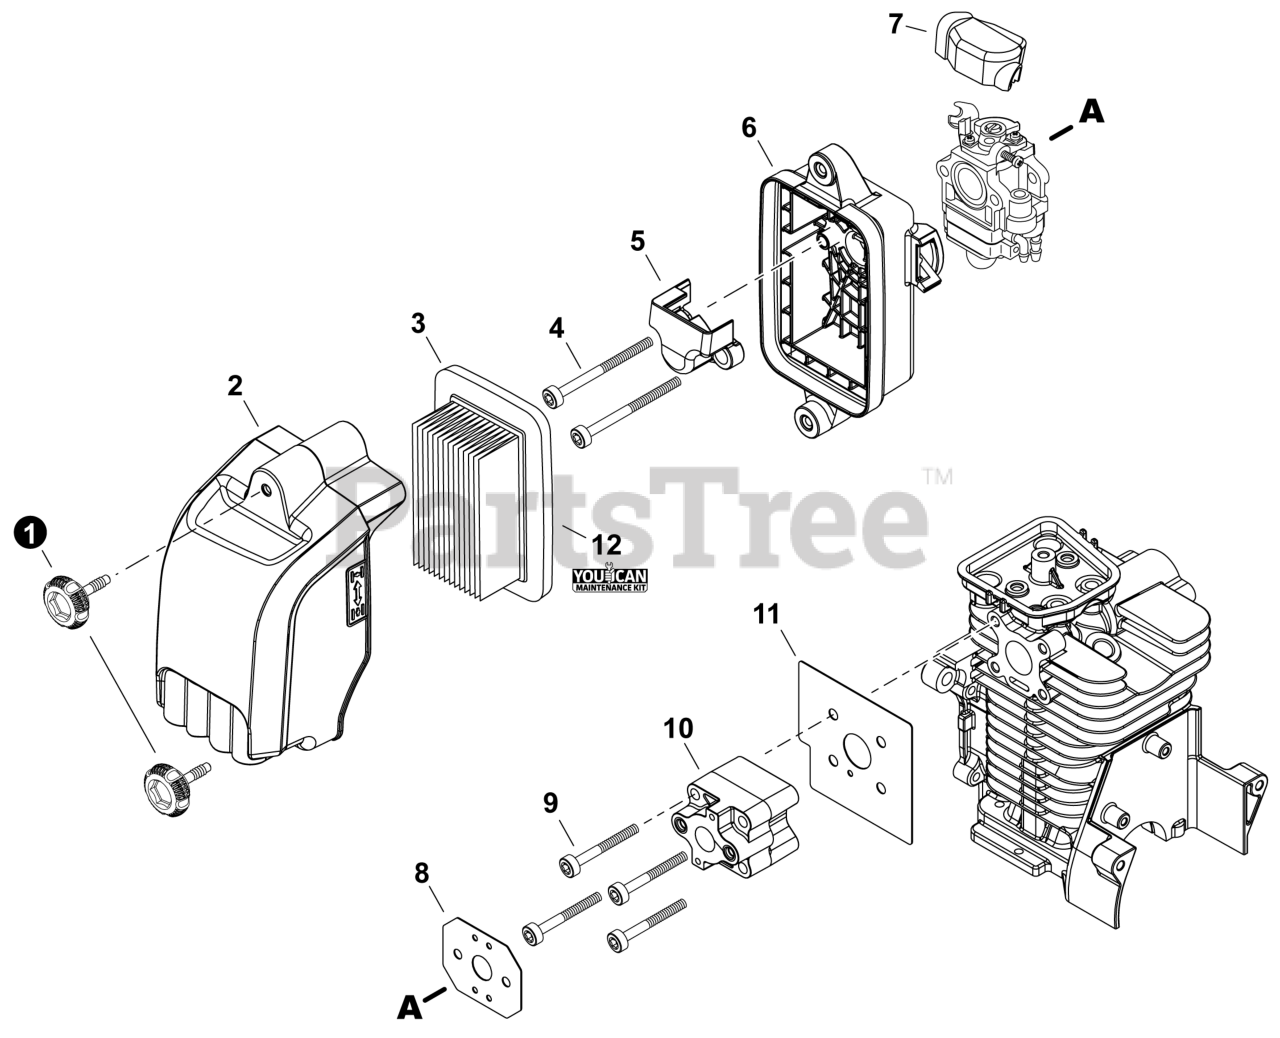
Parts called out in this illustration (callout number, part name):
1	THUMBSCREW
2	COVER, AIR FILTER
3	FILTER, AIR
4	BOLT, TORX 5x60
5	PLATE, PREVENT
6	CASE ASSY, AIR FILTER
7	CAP, CARBURETOR
8	GASKET, INTAKE
9	BOLT, TORX 5x40
10	INSULATOR, INTAKE
11	GASKET, INTAKE
12	TUNE-UP KIT - YOUCANT
